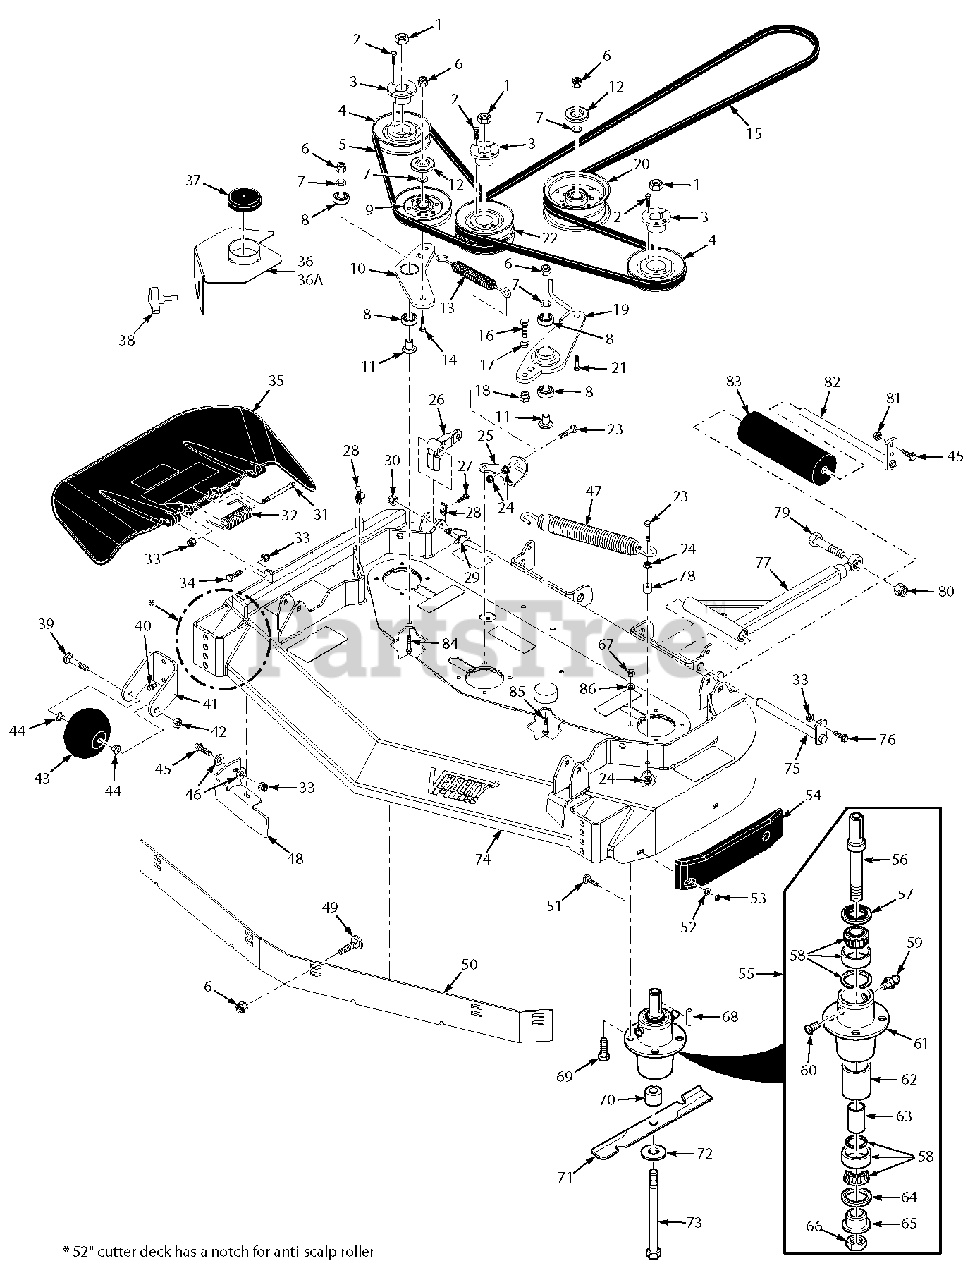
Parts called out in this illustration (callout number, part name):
1	Nut, 5/8-11 UNC
2	Bolt, Hex Head 1/4-20 x 1"
3	Hub, Tapered 1-1/8" Bore
4	Pulley 4.75"
5	Belt, RH Cutter Deck
6	Nut, Elastic Stop 3/8-16
7	Flatwasher, 3/8"
8	Bearing
9	Pulley, Idler 5" Dia.
10	Idler Arm
11	Idler Pivot
12	Dust Shield
13	Spring, Idler RH
14	Bolt, Hex Head 3/8-16 x 2"
15	Belt, Cutter Deck Drive (48V)
16	Bolt, Hex Head 7/16-14 x 1"
17	Lockwasher 7/16"
18	Boss, Spring Anchor
19	Idler Arm
20	Pulley, Idler 5" Dia.
21	Bolt, Hex Head 3/8-16 x 3"
22	Pulley, Double Groove
23	Bolt, Hex Head 3/8-16 x 1-1/2"
24	Nut, 3/8-16 Serrated Flange
25	Bracket, Spring Anchor RH (48V)
26	Lever, Deck Level
27	Bolt, Hex Head 3/8-16 x 2" Spec
28	U-Nut, 3/8-16
29	Bolt, Carriage 7/16-14 x 2-1/4"
30	Nut, Elastic Stop 7/16-14
31	Bolt, Hex Head 5/16-18 x 4-3/4"
32	Spring, Discharge Chute
33	Nut, Elastic Stop 5/16-18
34	Bolt, Hex Head 5/16-18 x 1-3/4"
35	Discharge Chute Assy.
35	CA Discharge Chute, 48V
36	Belt Cover Weldment RH
36	Belt Cover Weldment LH
37	Cap, Spindle
38	Wing Nut, 3/8-16
39	Bolt, Carriage 3/8-16 x 4"
40	Bolt, Serrated Flange 3/8-16 x 1"
41	Bracket, Anti-Scalp Wheel
42	Locknut, 3/8-16 Center Lock
43	Anti-Scalp Wheel
44	Bushing, .376 ID Oilite
45	Bolt, Hex Head 5/16-18 x 1"
46	Flatwasher, 5/16"
47	Spring, Idler LH
48	Turbo Baffle, Bolt On
49	Bolt, Carriage 3/8-16 x 1"
50	Baffle Custom-Cut, 48V (7-Position)
51	Bolt, Carriage 5/16-18 x 3/4"
52	Flatwasher, 5/16"
53	Nut, Center Lock 5/16-18
54	Wear Pad
55	Spindle Assembly
56	Shaft, Spindle
57	Seal Upper
58	Bearing Assembly
59	Grease Fitting
60	Valve, Grease Relief
61	Housing, Spindle
62	Spacer, Outside
63	Spacer, Inside
64	Seal, Lower
65	Bushing, Bottom
66	Nut, Special 1-1/16 - 18
67	Nut, Elastic Stop 5/16-18
68	Key, 1/4 x 1/4 x 2"
69	Bolt, Hex Head 5/16-18 x 1-3/4"
70	Spacer, Spindle
71	Cutter Blade 16.5"
72	Flatwasher, 5/8" Hardened
73	Bolt, Hex Head 5/8-11 x 9-1/2"
74	Cutter Deck Velocity Plus
75	Push Arm Shaft
76	Bolt, Hex Head 5/16-18 x 1"
77	Push Arm Assembly LH & RH
78	Spacer
79	Bolt, Hex Head 5/8-11 x 4-1/2"
80	Nut, Elastic Stop 5/8-11
81	Locknut, 5/16-18 Flange Hex Head
82	Shaft, Roller
83	Roller, Rear
84	Bolt, Hex Head 3/8-16 x 2-1/4"
85	Bolt, Hex Head 3/8-16 x 3-1/4"
86	Lockwasher 5/16"
